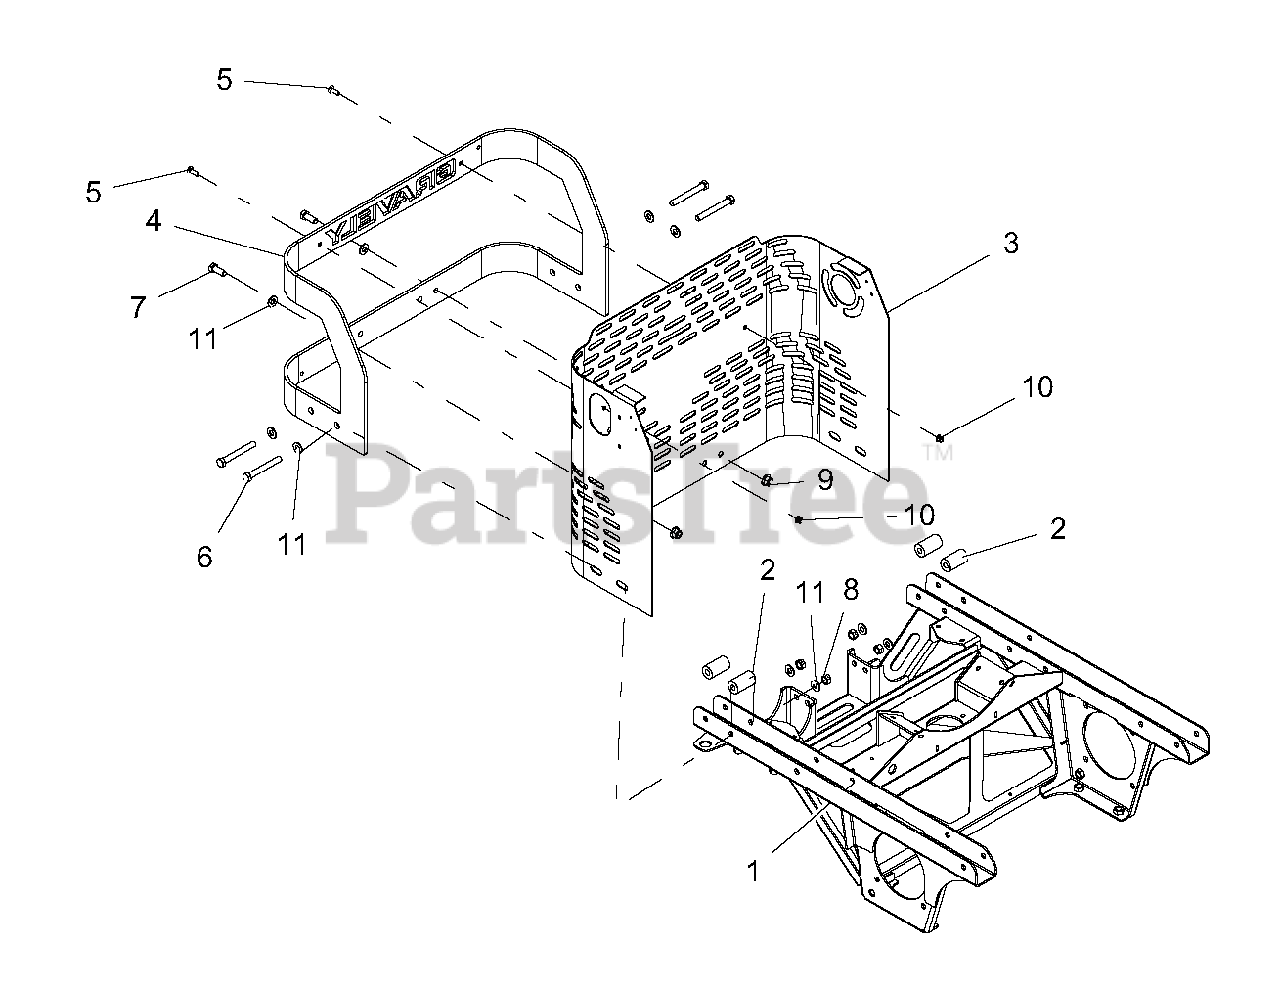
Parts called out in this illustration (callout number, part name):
1	WLDMT, ENGINE/ TRANSMISSION FRAME-RED
2	SPCR, BUMPER PT 400, DIESEL
3	GUARD, REAR PT400 DIESEL
4	BUMPER, PT400 REAR
5	@BLT-RDHDSQSHNK .31-18X1.00 G5 Y
6	BLT-HEX .50-13X4.00 GR5 YWZC
7	BLT-HEX .50-13X1.25 GR5 YWZC
8	@NUT-LK-CTR .50-13 YWZC
9	NUT-LK-NYL-FLG .50-13 YWZC
10	NUT-LK-NYL-FLG .31-18 YWZC
11	@WSHR-FL-STL.531X1.06X.095YWZC
